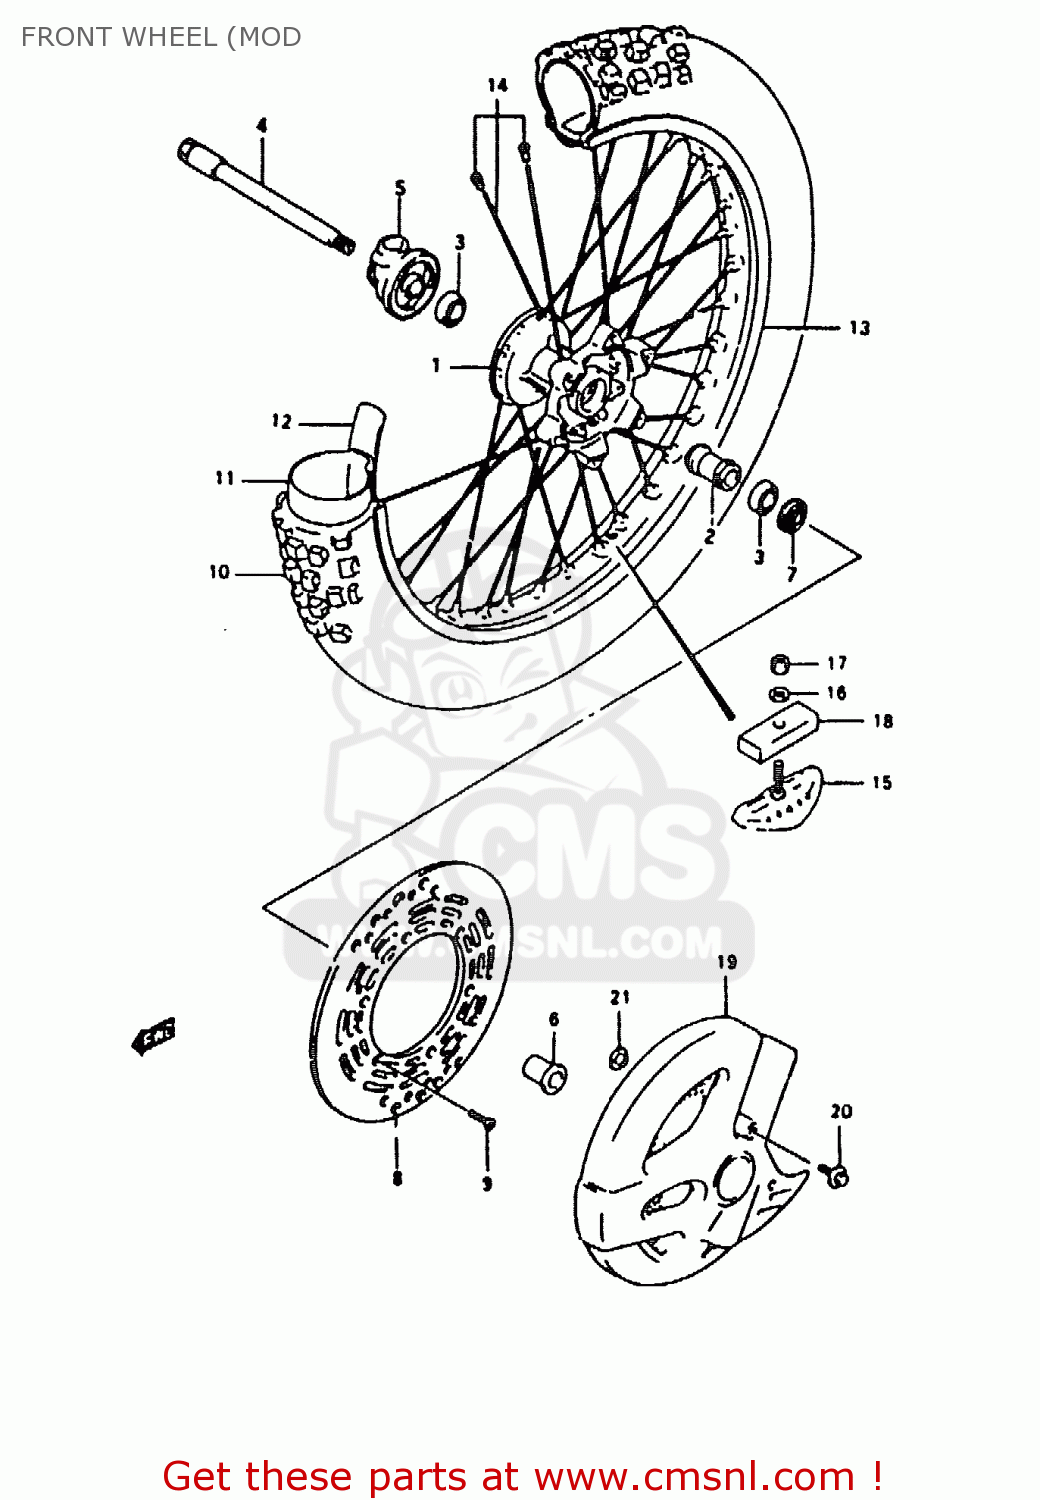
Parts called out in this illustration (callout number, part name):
1	HUB,FRONT WHEEL
2	SPACER,FR HUB BEARING
3	BEARING
4	AXLE,FR
5	BOX ASSY,SPEEDOMETER GEAR
6	SPACER,FR AXLE,L
7	SEAL,OIL(23X35X6)
8	DISC,FR BRAKE
9	SCREW
10	TIRE,FRONT 80/100-21
11	TUBE
12	PROTECTOR,WHEEL INNER
13	RIM,FRONT WHEEL (1.60X2
14	SPOKE SET,FR WHEEL
15	STOPPER,BEAD
16	WASHER
17	NUT
18	CUSHION,BEAD STOPPER
19	COVER,FRONT BRAKE DISC
20	BOLT(6X16)
21	BOLT
22	WASHER (8.5X16X1.6)
23	SCREW
24	SPACER(6.1X8X14.5)
25	WASHER(6.5X18X1)
26	WASHER(8.5X18X1)
